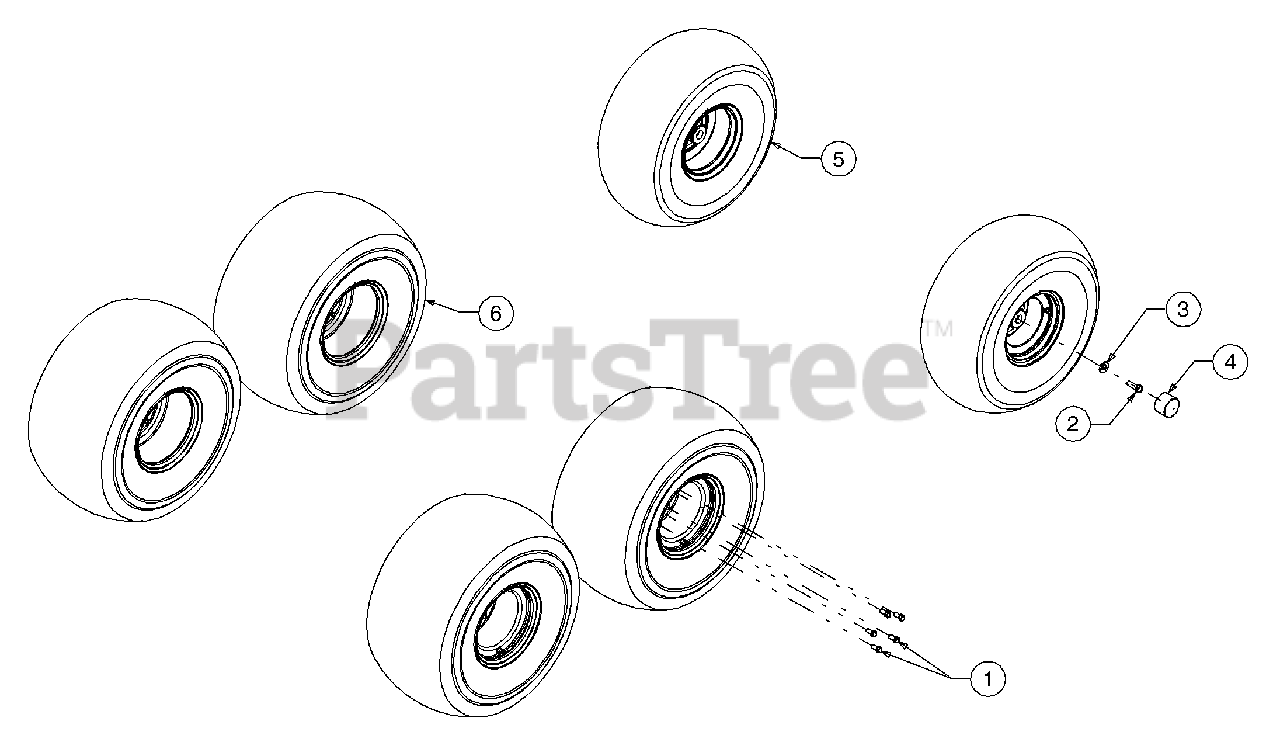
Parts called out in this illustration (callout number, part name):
1	Hex Screw, 7/16-20 x 1.5, Gr5
2	Hex Screw, 1/2-13 x 1.5, Gr5
3	Washer, Flat, .531 x 1.25 x .181
4	Dust Cover
5	Wheel Assembly, 22.5 x 10 x 8 (Standard)
6	Wheel Assembly, 25 x 12 x 9 (Standard)
